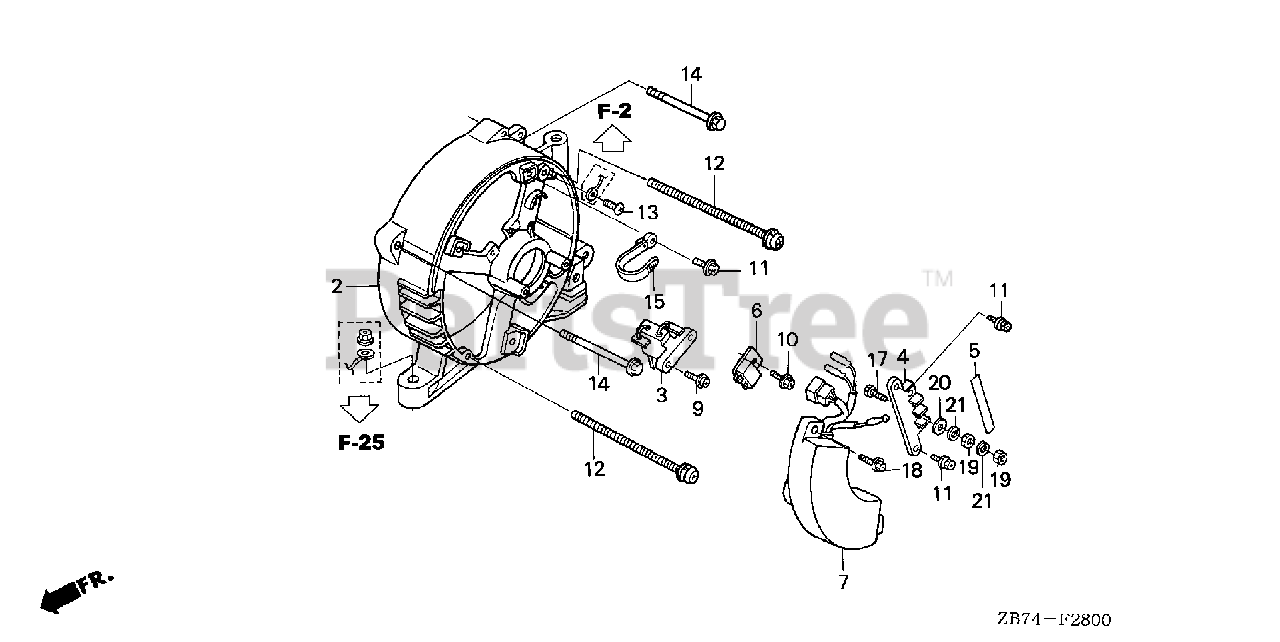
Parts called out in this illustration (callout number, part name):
2	HOUSING, RR. (NOT AVAILABLE)
3	BRUSH ASSY.
4	TERMINAL, VOLT CHANGE
5	MARK, VOLT
6	DIODE, D.C.
7	REGULATOR ASSY., AUTOMATIC VOLTAGE
9	SCREW, TAPPING (5X18)
10	SCREW, TAPPING (5X12)
11	SCREW, TAPPING (5X14)
12	BOLT-WASHER (5X155)
13	SCREW, PAN (5X12)
14	BOLT, FLANGE (6X120)
15	TIE, CABLE
17	BOLT, HEX. (5X20)
18	SCREW, TAPPING (5X16)
19	NUT, HEX. (5MM)
20	WASHER, PLAIN (5MM)
21	WASHER, SPRING (5MM)
